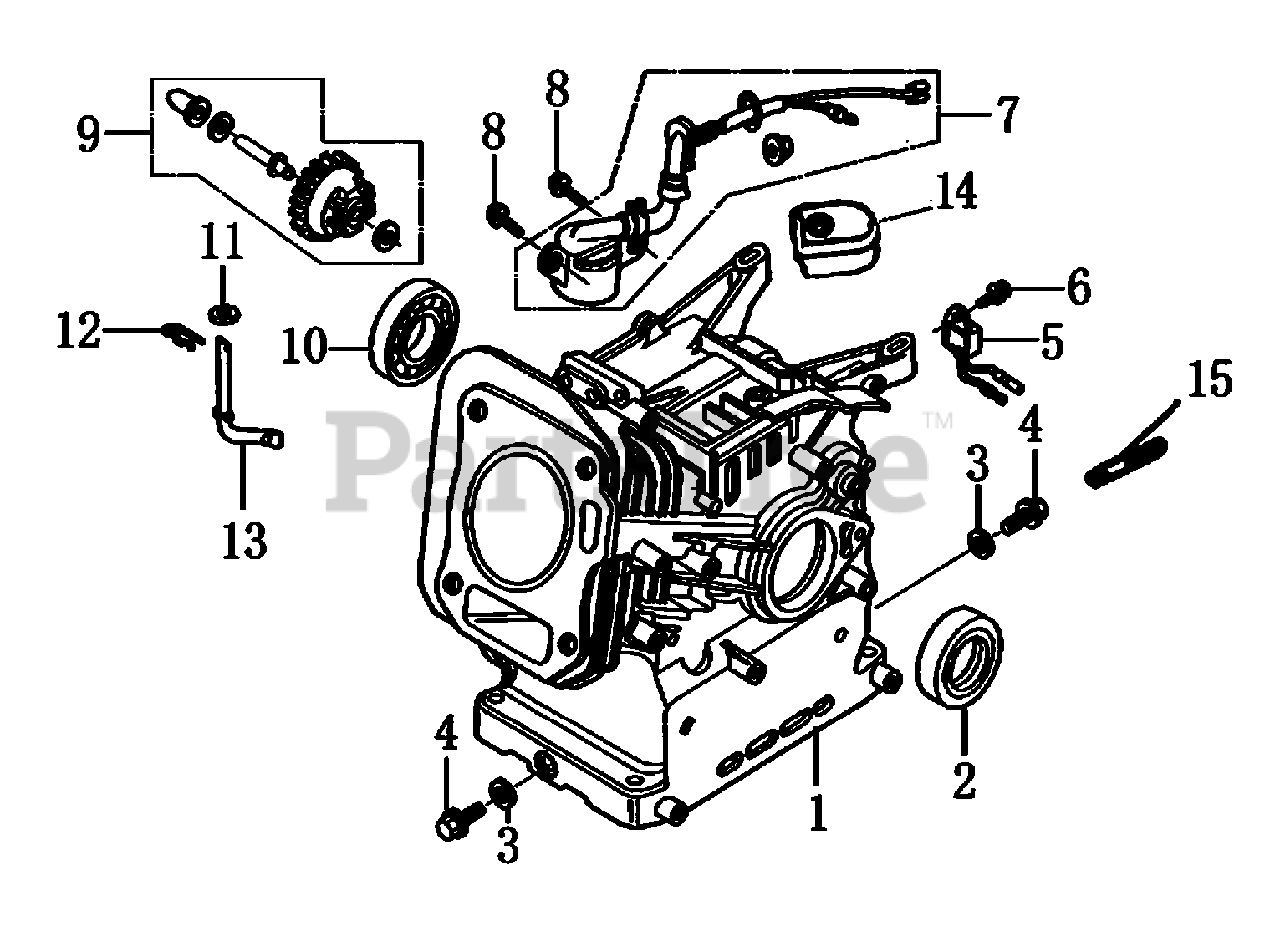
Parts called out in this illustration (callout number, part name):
1	CRANK CASE
2	OIL SEAL 25X41.25X6
3	WASHER, DRAIN PLUG
4	BOLT, DRAIN PLUG
5	ALERT UNIT, LOW OIL
6	BOLT, FLANGE , 6X10
7	OIL LEVEL SWITCH
8	BOLT, FLANGE , 6*14
9	GOVERNOR GEAR ASSY.
10	BEARING, RADIAL BALL
11	WASHER, PLAIN
12	PIN, LOCK
13	SHAFT, GOVERNOR ARM
14	COVER, WIRE
15	CABLE CLEAT
